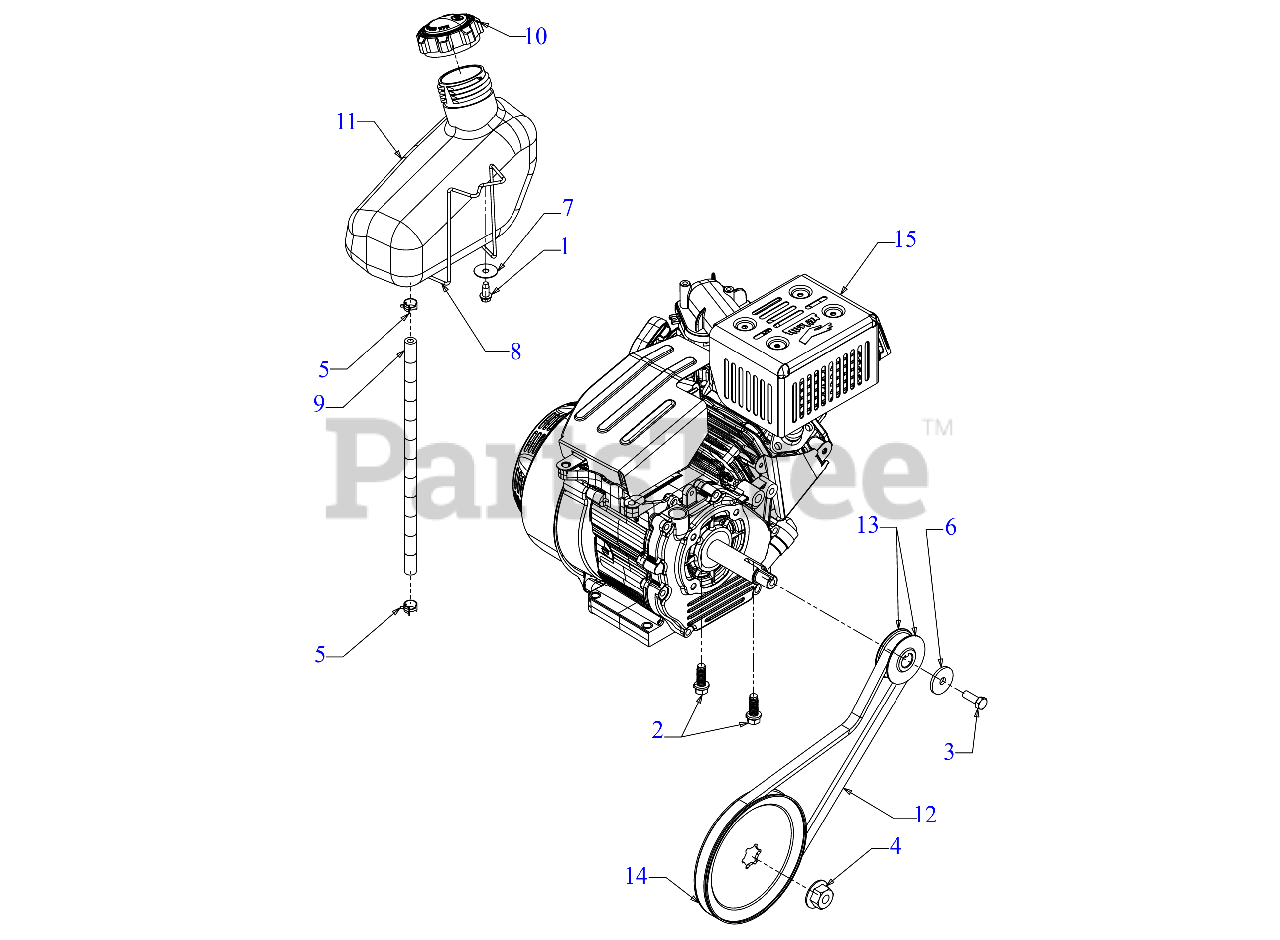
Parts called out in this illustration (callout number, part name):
1	SCREW 1/4-10:.625
2	SCREW 3/8-16 x 1
3	SCREW 5/16-24 x .875 GR5
4	FLANGE NUT W/HUB
5	HOSE CLAMP 1/20
6	WASHER-5/16 x 1.25X 1.27
7	FLAT WASHER
8	SUPPORT WIRE
9	FUEL HOSE LOW PERMEATION 13"
11	FUEL TANK (2 QT)
12	V-BELT .500 x 35.00LG
13	HALF PULLEY
14	AUGER PULLEY
15	COMPLETE ENGINE 123cc
